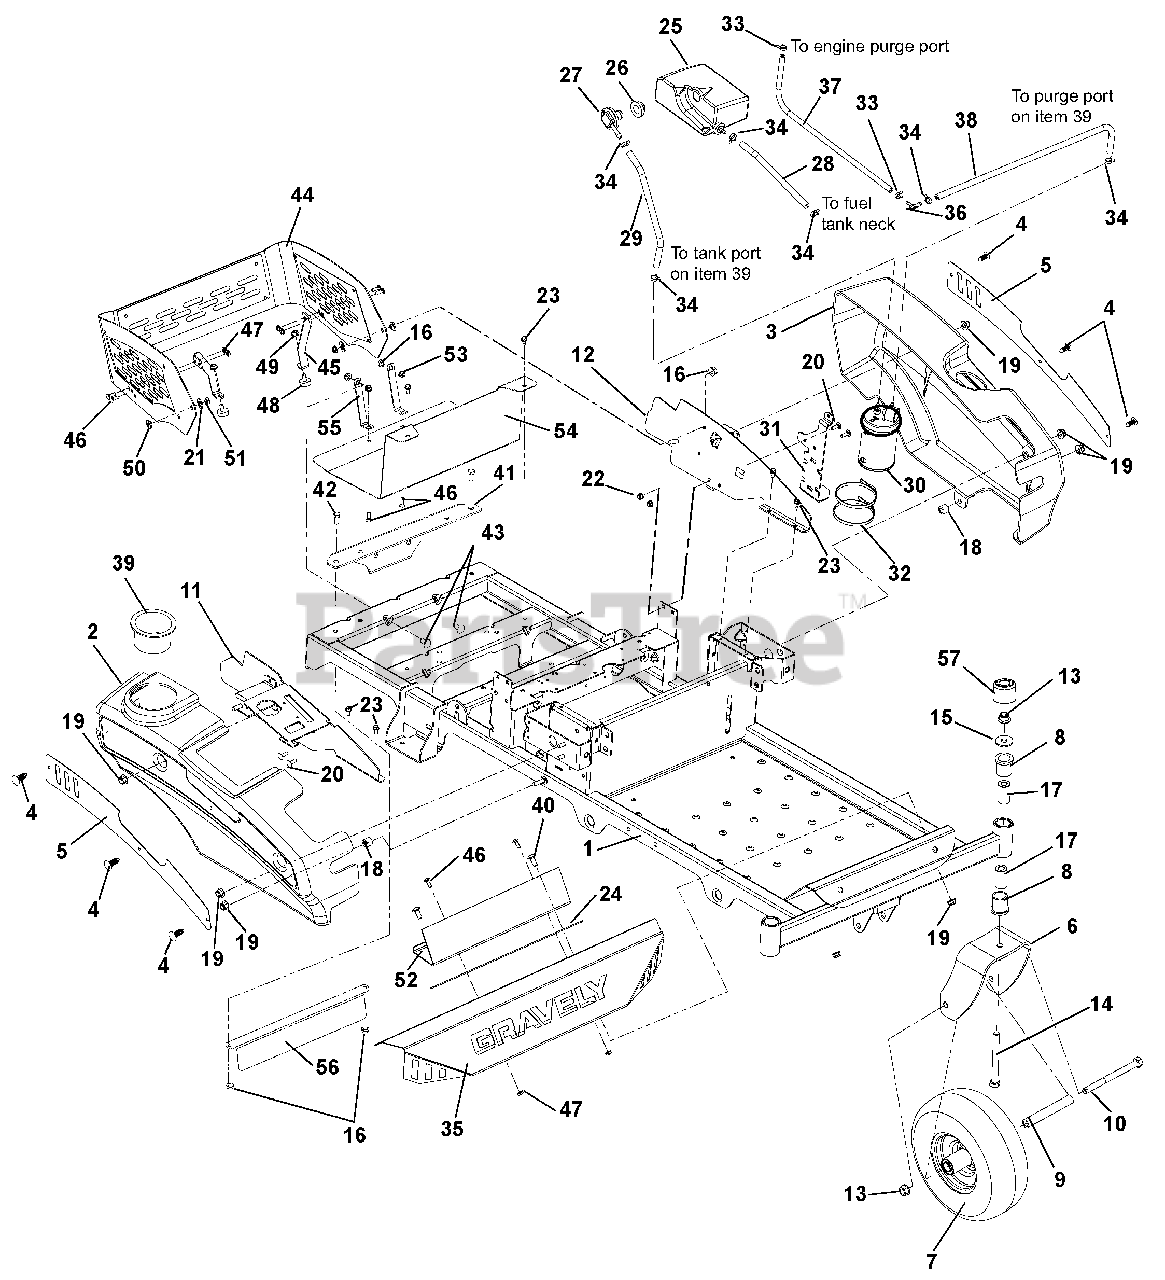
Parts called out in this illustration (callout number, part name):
1	Weldment, Frame
2	Fender, Right Hand
3	Fender, Left Hand
4	Rivet, Nylon
5	Plate, Fender
6	Fork, Caster
7	Wheel/Tire Assembly, 11 x 4-5
8	Bushing, Flange 1.00 x 1.25 x 1.50 x 1.50
9	Spacer, Wheel
10	Bolt, Hex .50-13 x 6.50
11	Weldment, Fender Mount Right Hand
12	Weldment, Fender Mount Left Hand
13	Nut, Locking Top Flange .50-13
14	Bolt, Hex .50-13 x 5.00
15	Washer, Flat Steel .511 x 1.441 x .125
16	Nut, Locking Top Flange .38-16
17	Spacer, Caster
18	Bushing, Sleeve .391 x .688 x .52
19	Nut, .31-18 Nyloc Flange
20	Bolt, Round Head Square Neck .25-20 x .75
21	Washer, Flat Nylon .52 x 1.00 x .08
22	Nut, .25-20 Nyloc Flange
23	Screw, Tapping .25-20 x .50 Hex Washer Head Thread
24	Grip, Adhesive (1" x 16" BLK)
25	Expansion Tank Subassembly
26	Grommet, Remote Vent Nitrile
27	Vent, Roll-Over (.25" ID Hose)
28	Hose, .25 Low-Perm Bulk Gas
29	Hose, .25 Low-Perm Bulk Gas
30	Carbon Canister, 300CC
31	Bracket, Mount, Canister BBZ
32	Plastic Tie Strap Large
33	Clamp, Hose Spring .188
34	Clamp, Hose Wire .490/.510 x .116
35	Foot Rest
36	Fitting, 3/16 x 1/4 90 Deg Vac
37	Hose, .188 Low Perm Bulk (915168)
38	Hose, .25 Low Perm Bulk Gas (915168)
39	Cupholder
40	Bolt, Round Head Square Neck .31-18 x .75
41	Plate, BBZ Hitch Kit Plate (915170)
42	Bolt, Hex .38-16 x 1.00
43	Bolt, Round Head Square Neck .38-16 x 1.00
44	Assembly, Engine Wrap
45	Bracket, Engine Wrap Foot
46	Bolt, Round Head Square Neck .25-20 x .50
47	Nut, Center Lock Flange .25-20
48	Bumper, Rubber
49	Nut, Serrated Flange .31-18
50	Bushing, Flange .325 x .499 x .3 x .875
51	Nut, Center Lock Flange .31-18
52	Plate, Back Foot Rest
53	Nut, Locking Top Flange .25-20
54	Guard, Heat Shield (ZT)
55	Strap, Heat Shield (ZT)
56	Guard, Hot Surface (ZT)
57	Cap, Dust
